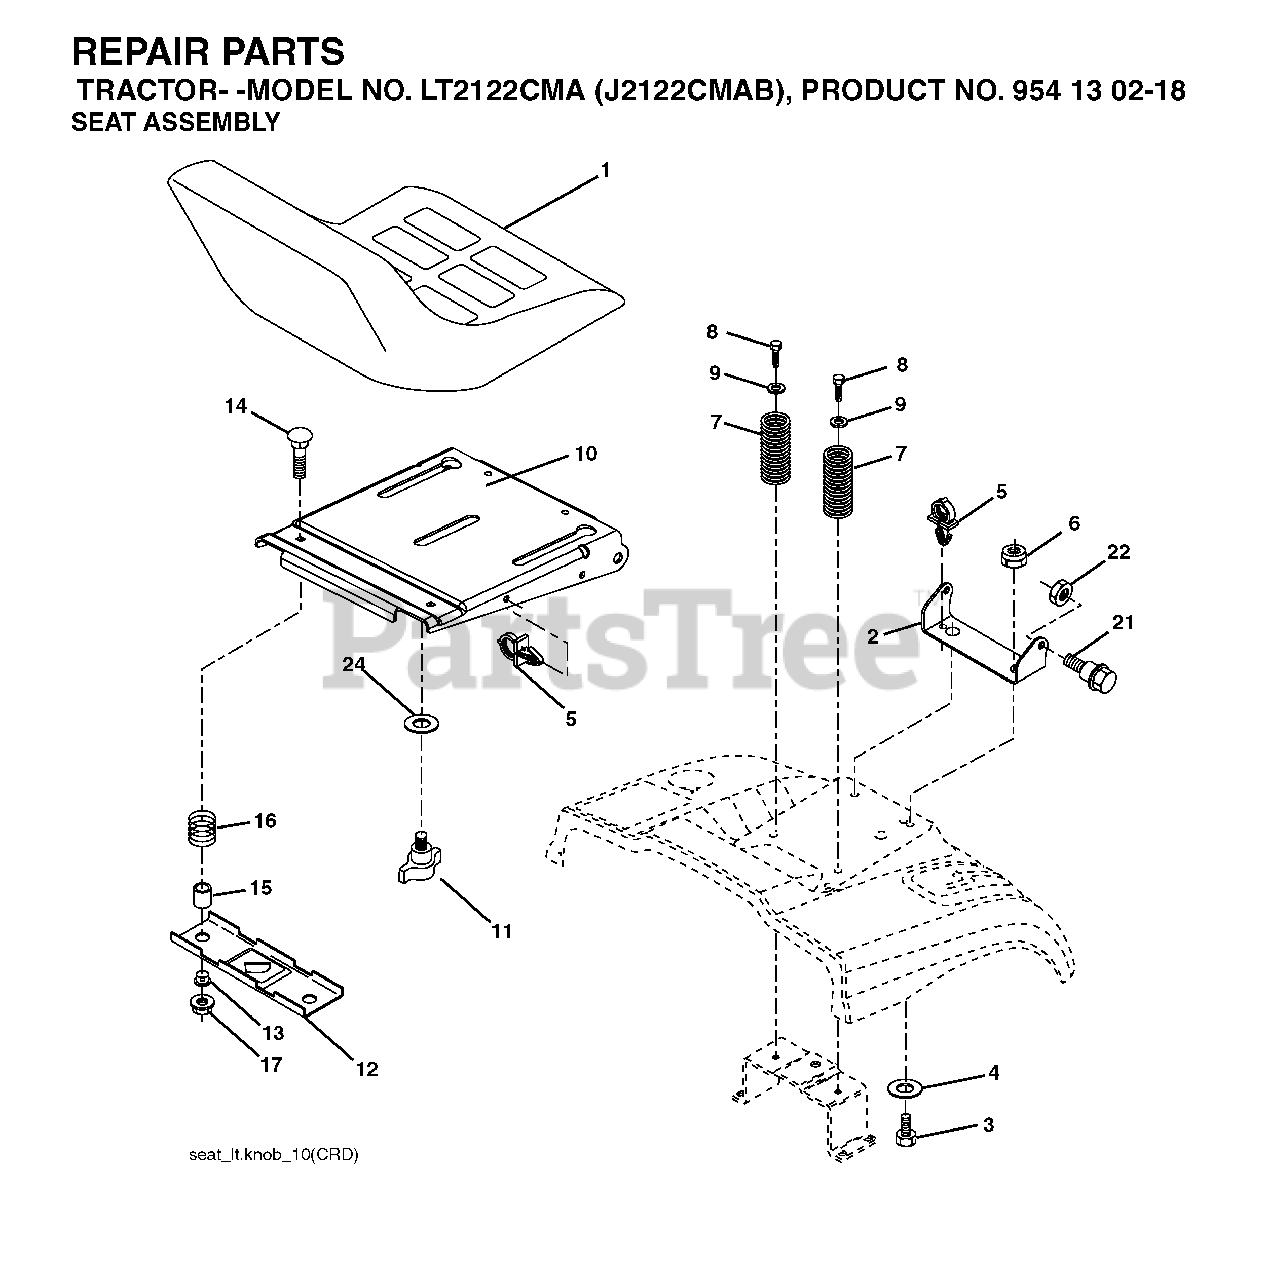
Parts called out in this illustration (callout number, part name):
2	BRKT.PIVOT.FENDER
4	WASHER PM
5	PUSH CLIP
6	NUT
7	SPRING COMPRESSION
8	SCREW 3/8-16X1
9	WASHER
11	KNOB.SEAT.ADJ.WINGNUT
12	BRKT SWITCH
14	BOLT.ROUND.HEAD.SQUARE.NECK
15	SPACER SPLIT
16	SPRING COMPRESSED
17	NUT T
21	BOLT.SHOULDER.5/16-18
22	NUT.71038.31-18.HEX.NYLOCK
